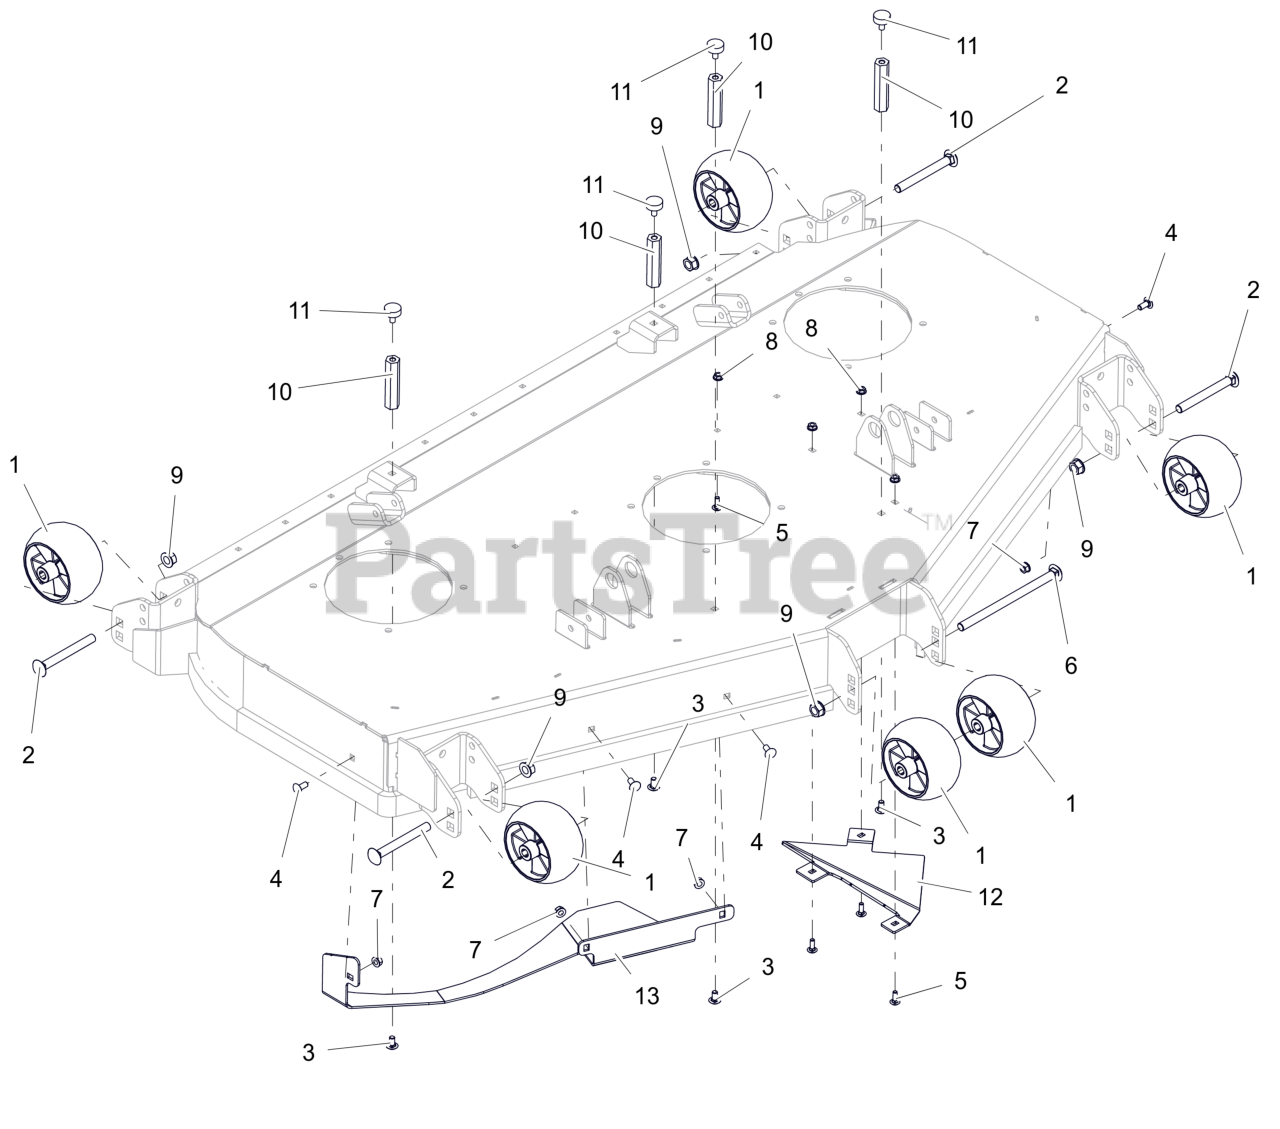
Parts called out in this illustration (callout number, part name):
1	WHEEL, ANTI SCALP - 5X3 CTR W/RIBS
2	BLT,RHSN .50-13X4.50 G5 ZCC
3	BLT,RHSSN.31-18X.625 G5 ZCCP30
4	BLT, RHSSN.31-18X.750 G5 ZCC
5	BLT, RHSN .25-20X.750 G5 ZCC
6	BTL,RHSN .500-13 X 8 G5 ZCC
7	NUT,LK-CTR-FLG .31-18 GF ZCC
8	NUT-LK-CTR-FLG .25-20 ZC120
9	NUT-LK-CTR-FLG .500-13 GG ZCC
10	NUT, COUPLING .312-18 X 3.375
11	BUMPER, RUBBER
12	BAFFLE, INSERT TRIANGLULAR (ORANGE)
13	DEFLECTOR, BAFFLE BOLT-IN (ORANGE)
